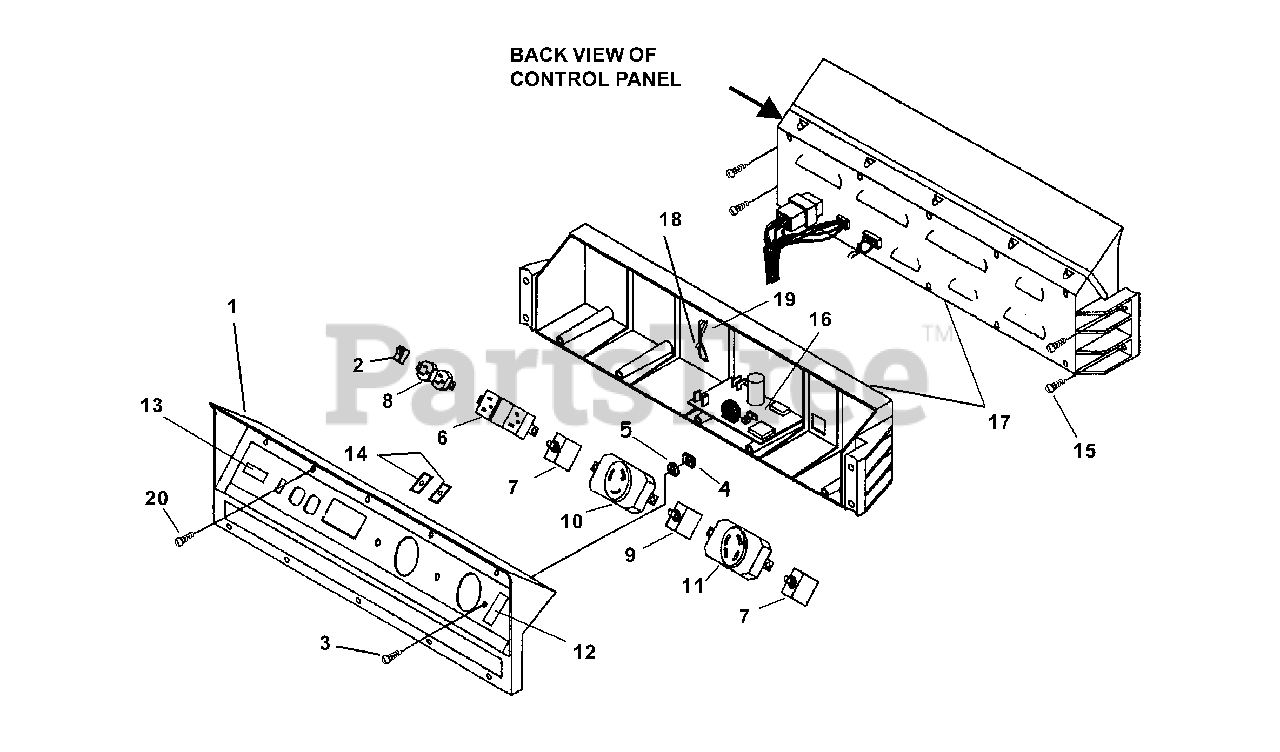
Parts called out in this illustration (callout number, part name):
1	Control Panel
2	Switch
3	Screw-Pan Hd. (8-32 X 7/8")
4	Nut-Hex
5	Washer-Lock
6	Receptacle (GFCI)
7	Circuit Breaker (20 amp)
8	Receptacle-Duplex
9	Circuit Breaker (30 amp)
10	Receptacle-Locking (120V)
11	Receptacle-Locking (240V)
12	Volt Meter
13	Hour Meter
14	Rubber Bumper
15	Screw-Torx Hd. (10-24 X 1/2")
16	Control Board
17	Control Panel-Back
18	Clip, Tie
19	Tie, Cable
20	Screw, Plastite (8-16 X 3/4")
